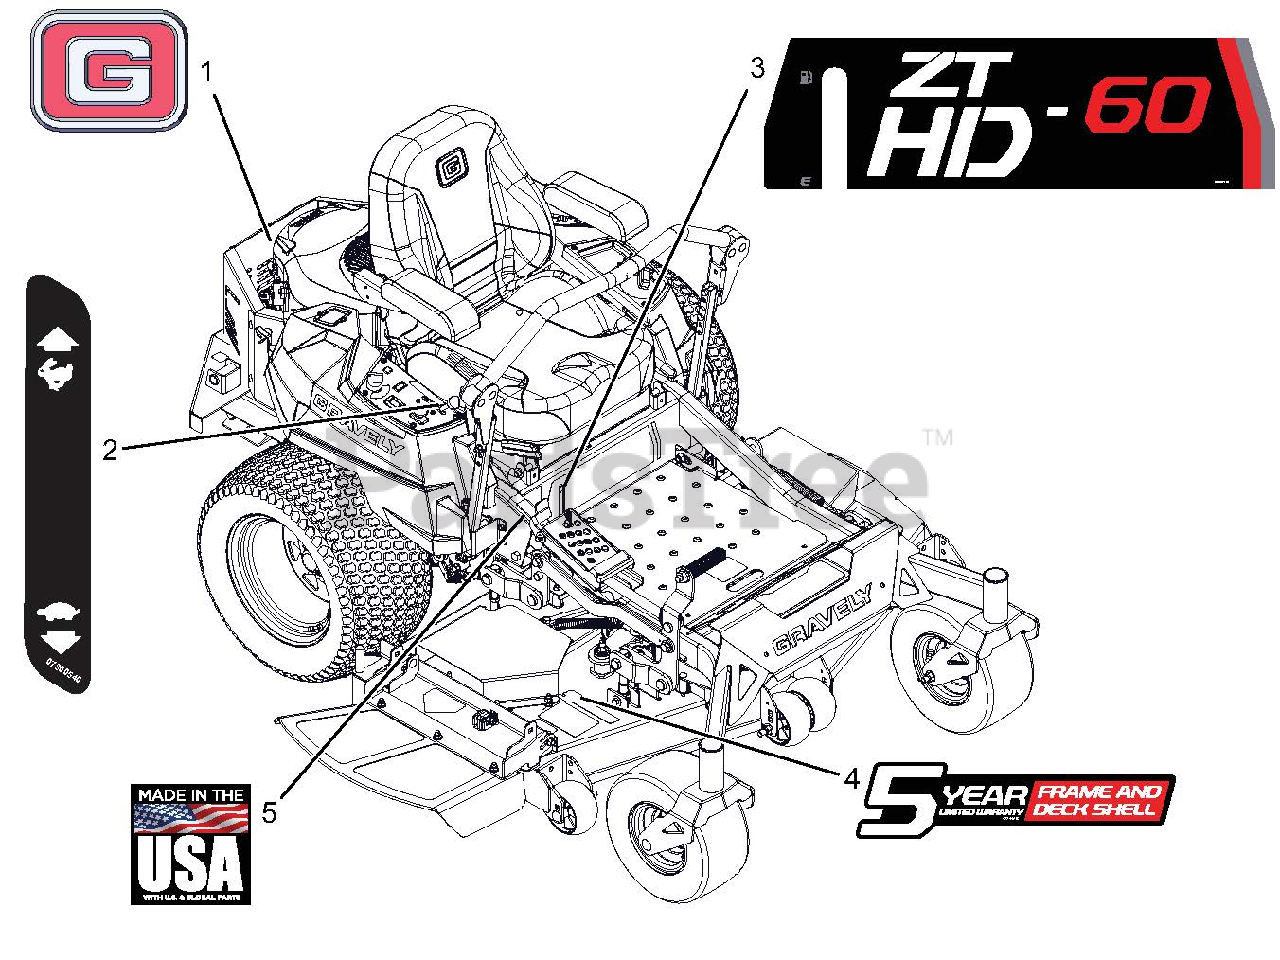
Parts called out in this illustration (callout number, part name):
1	DECAL, GRAVELY BRAND
2	DECAL, DASH DECAL
3	DECAL - 60HD
4	DECAL, DECK 5 YEAR-GRAVELY
5	DECAL, MADE IN USA
